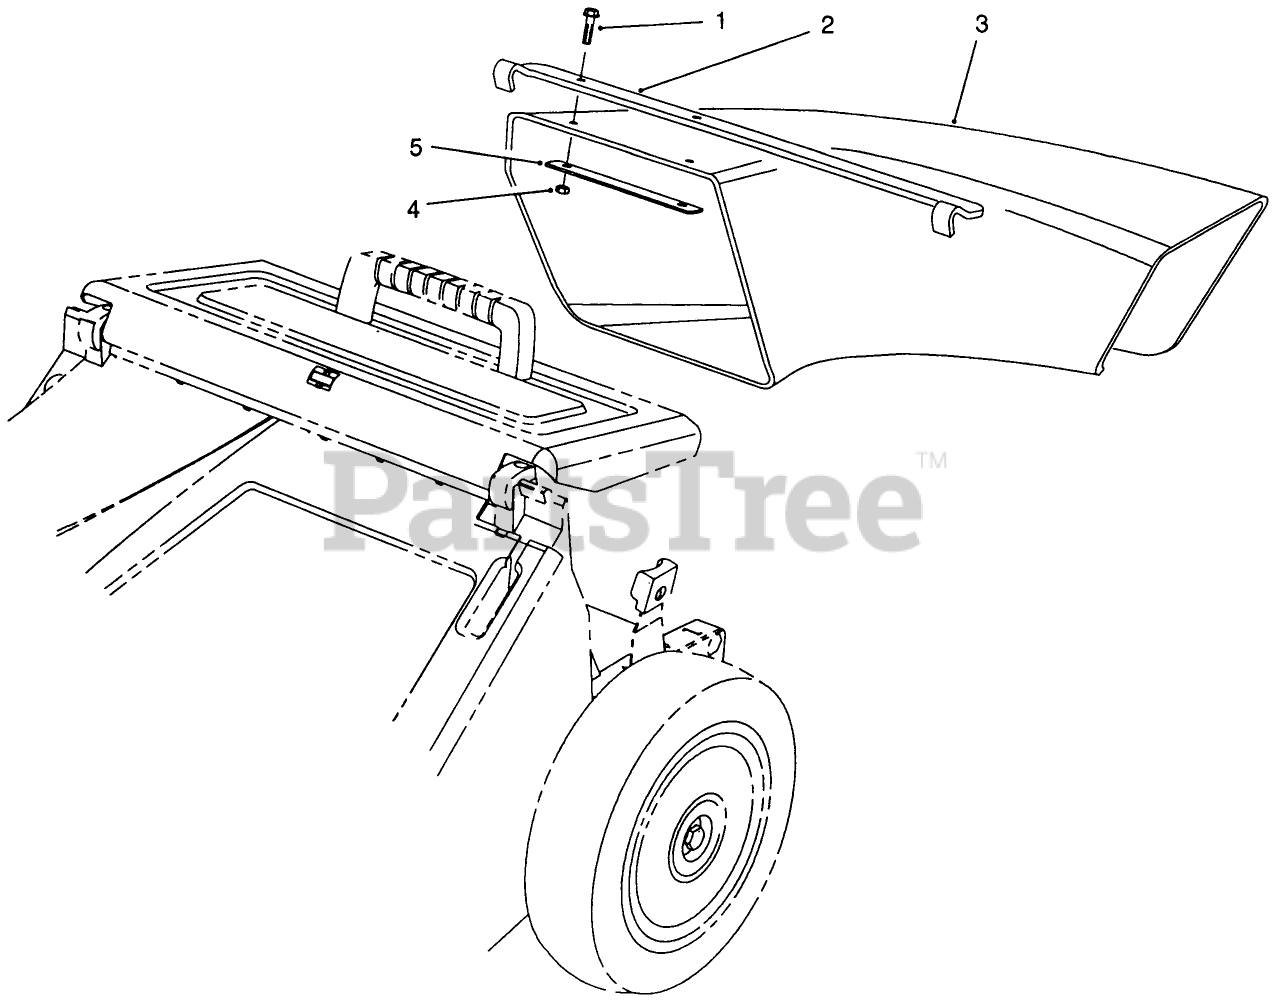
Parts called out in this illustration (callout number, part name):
1	SCREW-HWH
2	CHUTE HANGER BRACKET*
4	NUT-LOCK, NI
